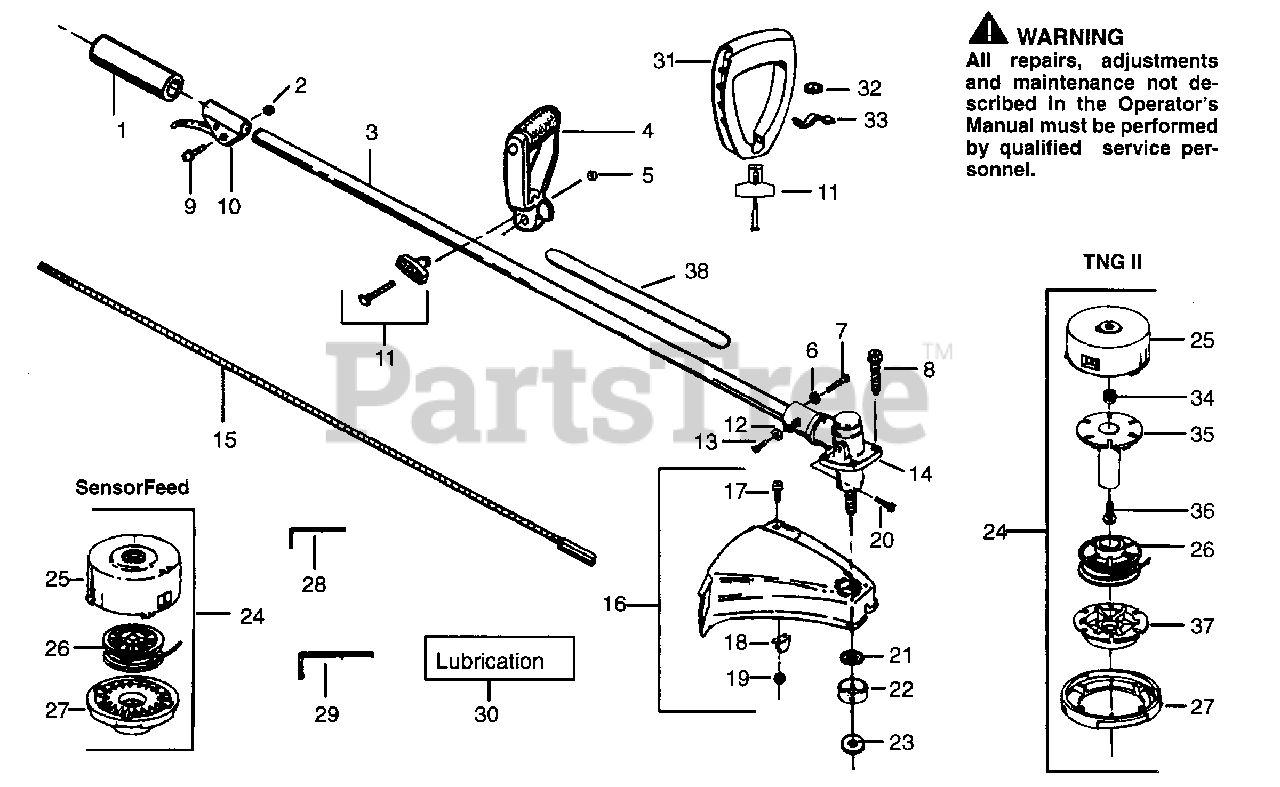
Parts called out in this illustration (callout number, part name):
1	Drive Shaft Grip
3	Drive Shaft Housing
6	Lockwasher
10	Throttle Lever Ass'y. w/ Lock
11	"T" Handle Ass'y.
12	Lockwasher
14	Gear Box Ass'y.
15	Drive Shaft
16	Shield Kit Ass'y.
18	Line Limiter
19	Locknut
22	Dust Cup
23	Grass Washer
24	SensorFeed
24	TNG II Single Exit
25	SensorFeed
26	SensorFeed
26	TNG II
27	Sensorfeed
28	Hex Wrench (5/32)
29	Hex Wrench (3/16)
30	Shaft Lubrication
35	Locking Plate
37	Release Button
38	Decal-Shaft Warning
